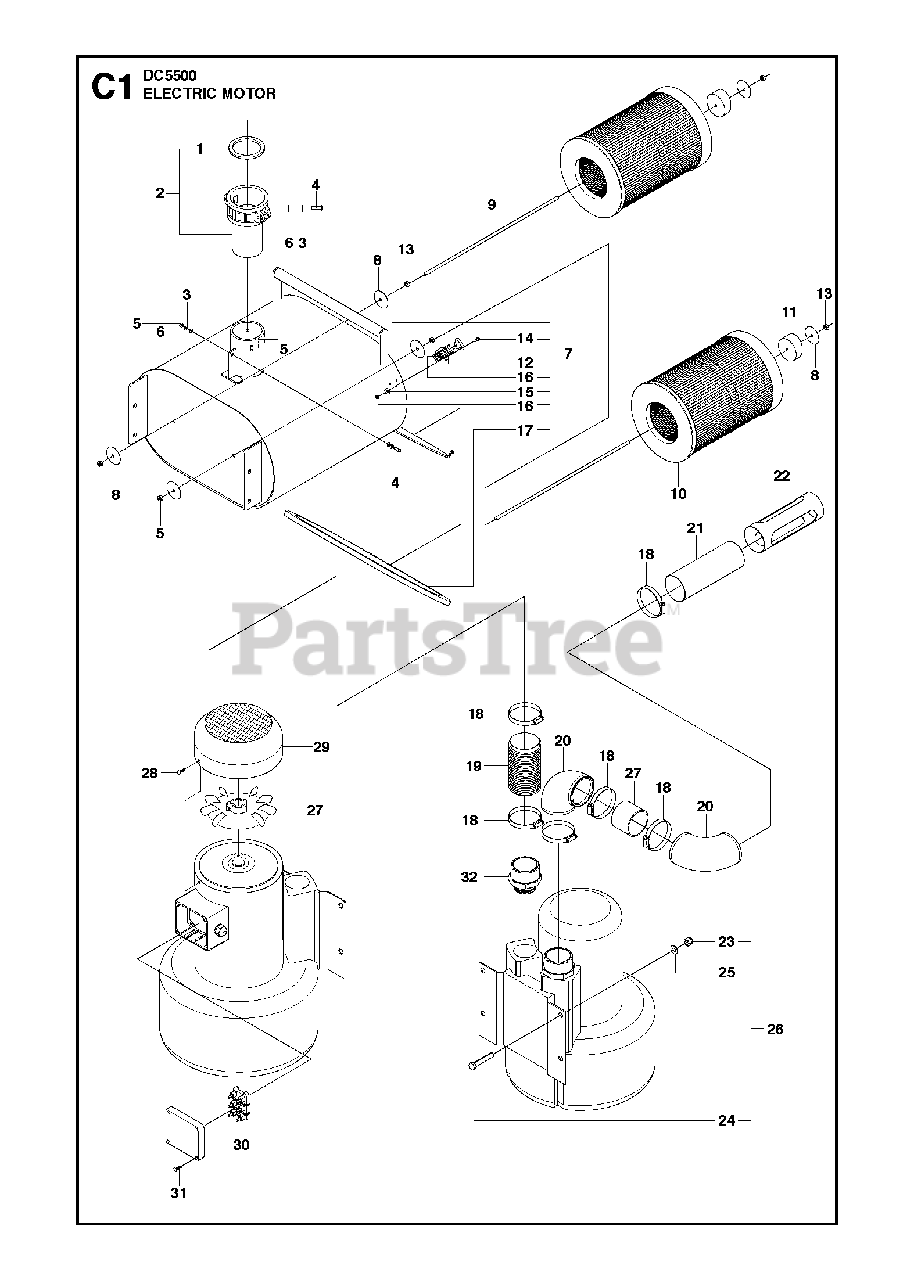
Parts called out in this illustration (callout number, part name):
3	WASHER
5	HEXAGON LOCKING NUT
13	HEXAGON NUT
16	HEXAGON LOCKING NUT
25	WASHER
31	SCREW CRPANM
